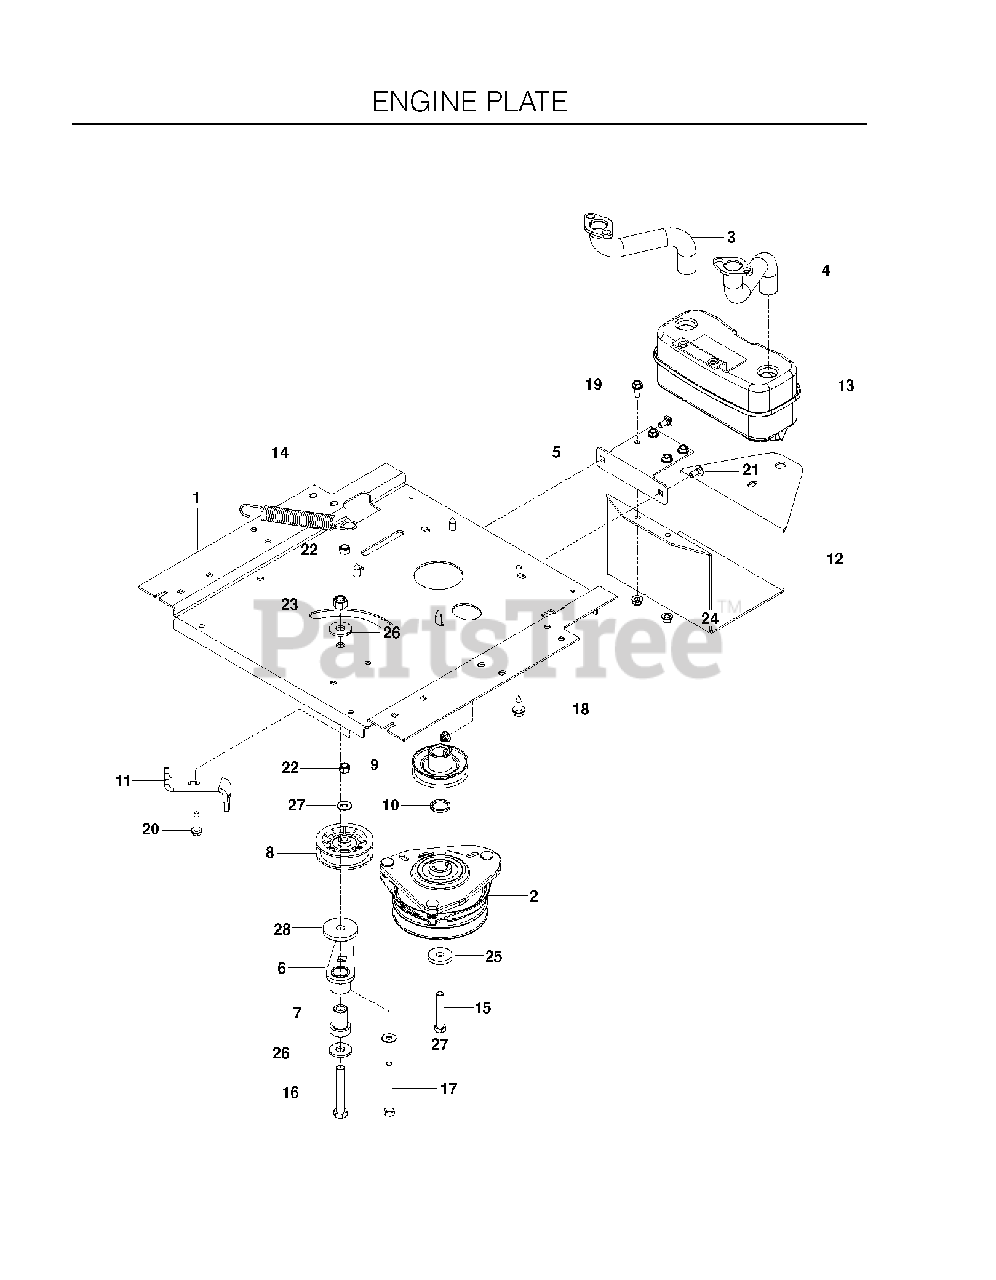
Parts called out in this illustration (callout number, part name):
1	PLATE, ENGINE BLK
3	TUBE
4	EXHAUST TUBE RH
5	BRACKET, MUFFLER, BLACK
6	IDLER ARM
7	IDLER SPINDLE
8	PULLEY, IDLER
9	PULLEY, ENGINE
10	HUB PULLEY SPACER
12	GUARD, MUFFLER, BLACK
13	MUFFLER ASM TWIN
14	SPRING.DRIVE.DECK.2006
15	HCS 7/16-20 X 2.5 GR8
16	HCS 1/2C X 3 1/4
17	HCS 3/8-16X3 1/2 GR5
18	HHFS 3/8-16 X 1.0 THD FORMING
19	BOLT 5/16-18 X 3/4
21	BOLT 5/16C X 3/4" CARRIAGE
22	NUT 3/8-16 NYLOC
23	NUT 1/2-13 HEX NYLOC ZD
24	5/16-18 NYLOC FLANGE NUT
26	WASH USS FLAT 1/2
27	WASHER 5/16 FLAT
28	HEAVY WASHER
